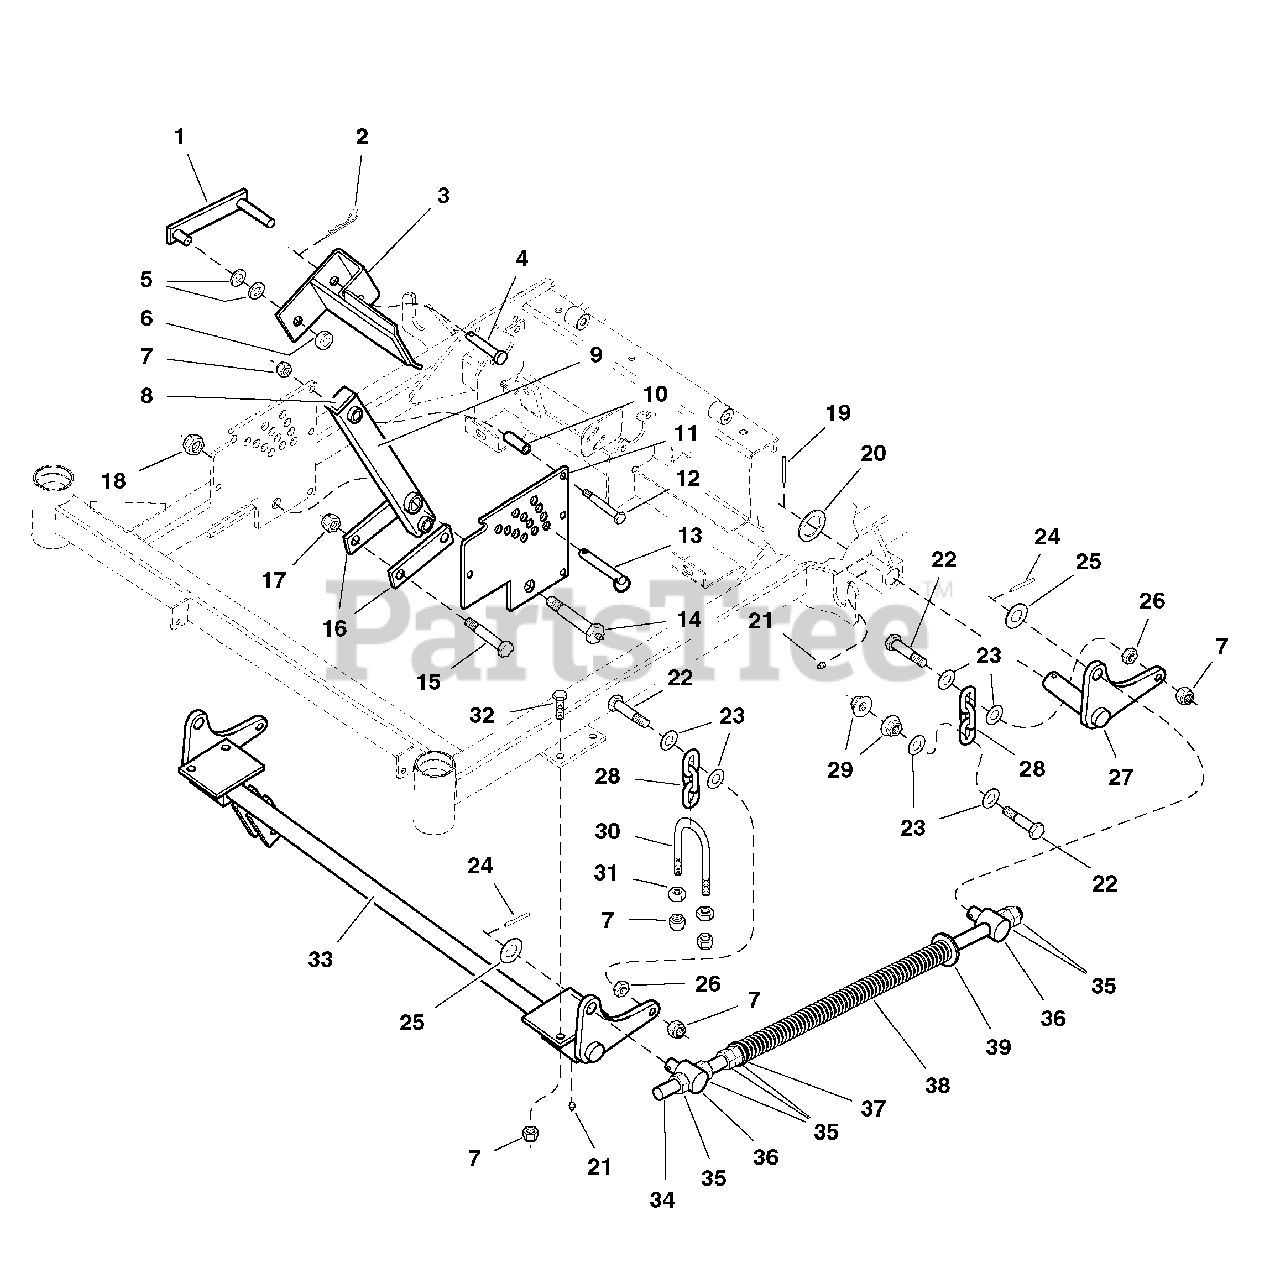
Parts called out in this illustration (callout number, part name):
1	DECK LIFT LOCK
2	HAIRPIN CLIP
3	DECK LIFT PEDAL
4	PIN, Clevis, 1/2 x 2-1/2
5	WASHER, 1/2
6	COLLAR, Set, 1/2
7	NUT, Hex, Nylon Lock, 3/8-16
9	ARM, Deck Lift Pivot
10	SPACER, Lift Plate
11	DECK HEIGHT PLATE
12	CAPSCREW, Hex Hd, 3/8-16 x 2-3/4
13	PIN, 1/2 x 3
14	LIFT PIVOT BOLT
15	CAPSCREW, Hex Hd, 1/2-20 x 3
16	LINK, Deck Lift
17	NUT, Hex, Nylon Lock, 1/2-20
18	NUT, Hex Jam, Nylon Lock, 5/8-11
19	PIN, Roll, 3/16 x 1-1/2
21	GREASE FITTING
22	CAPSCREW, Hex Hd, 3/8-16 x 1-3/4
23	WASHER, 3/8
24	PIN, Spring, 3/16 x 1-1/4
25	WASHER, 5/8
26	NUT, Hex Jam, 3/8-16
27	DECK LIFT PIVOT-LH
28	CHAIN, 3 Links
29	NUT, Hex, Serrated Flange, 3/8-16
31	NUT, Hex, 3/8-16
32	CAPSCREW, Hex Hd, 3/8-16 x 1-1/4
33	DECK LIFT SHAFT & MOUNT ASSEMBLY
35	NUT, Hex, 5/8-11
36	SPRING ROD PIVOT
38	SPRING, Deck Lift
39	WASHER, USS, 5/8
